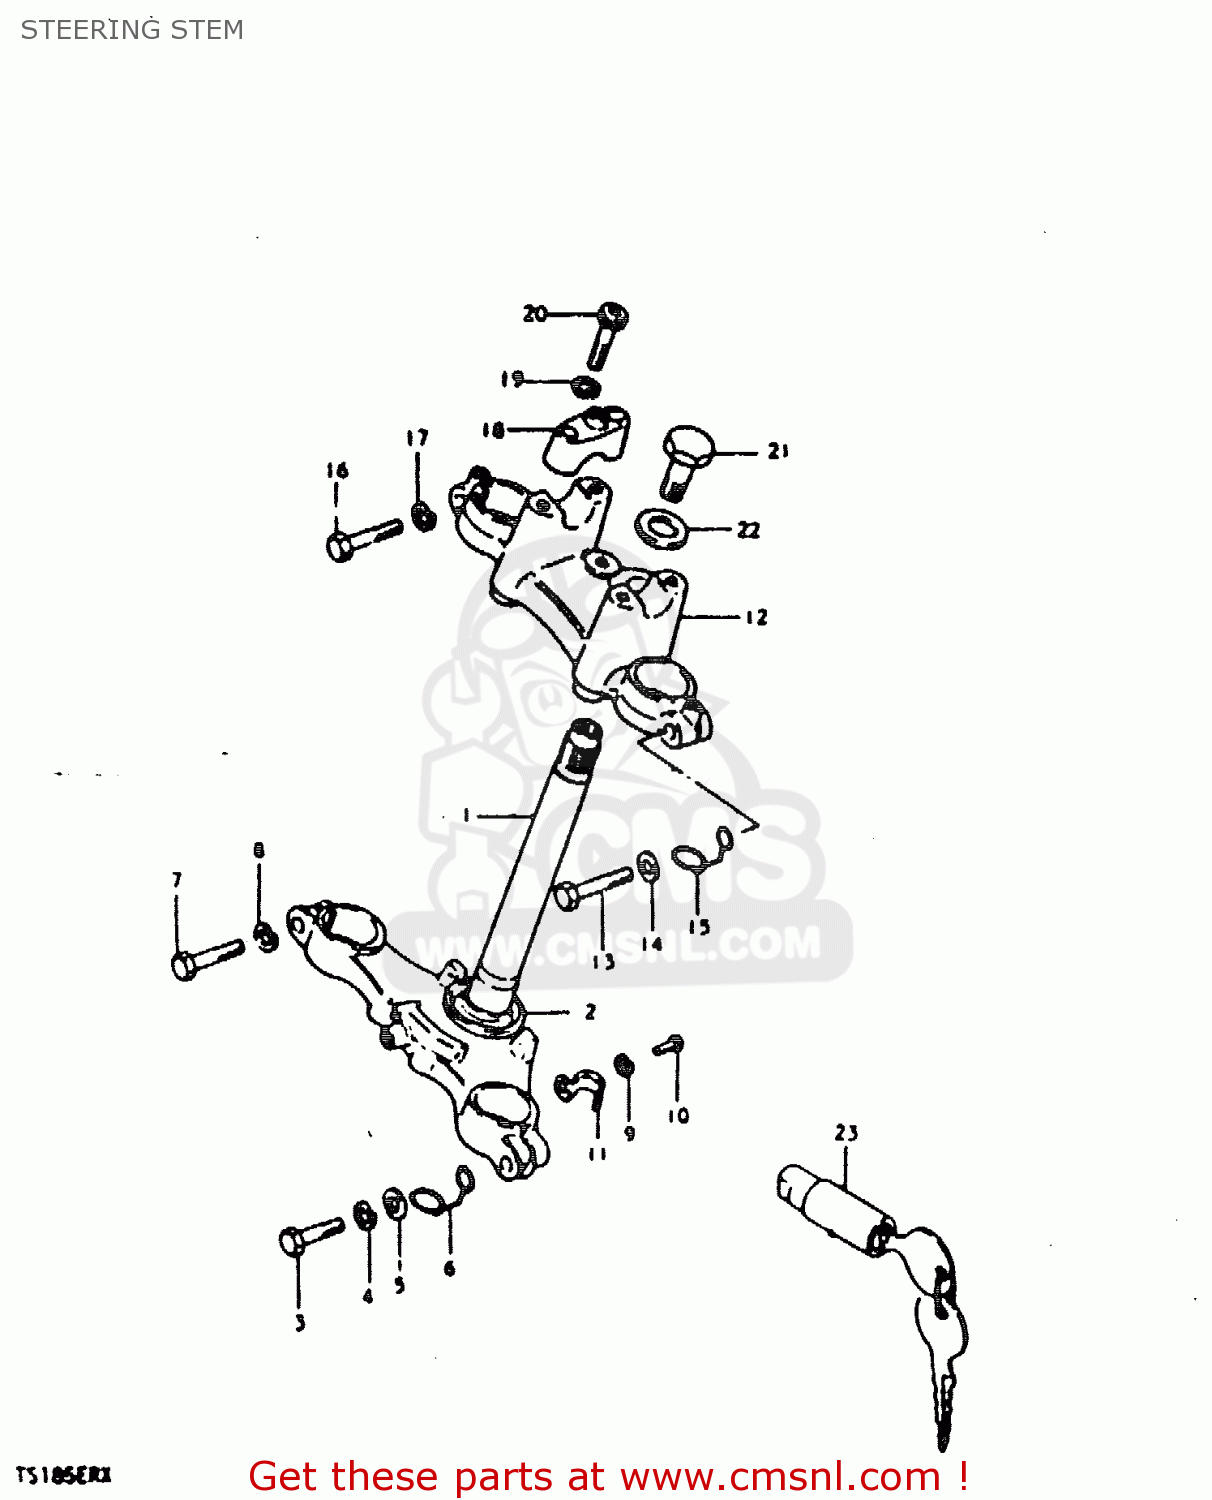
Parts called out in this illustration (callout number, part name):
1	STEM,STEERING
2	RACE,STEERING OUTER LWR
3	BOLT
4	WASHER,LOCK 12
5	WASHER
6	CLIP
7	BOLT
8	WASHER,LOCK 12
9	LOCK WASHER
10	SCREW
11	CLIP,BRAKE CABLE
12	HEAD,STEERING STEM(GOLD)
13	BOLT 10X40
14	WASHER
15	CLIP
16	BOLT 10X40
17	LOCK WASHER
18	HOLDER,HANDLEBAR(GOLD)
19	LOCK WASHER
20	BOLT 8X35
21	BOLT,FORK INNER TUBE
22	WASHER,STEM HEAD(10.5X30X3.2)
